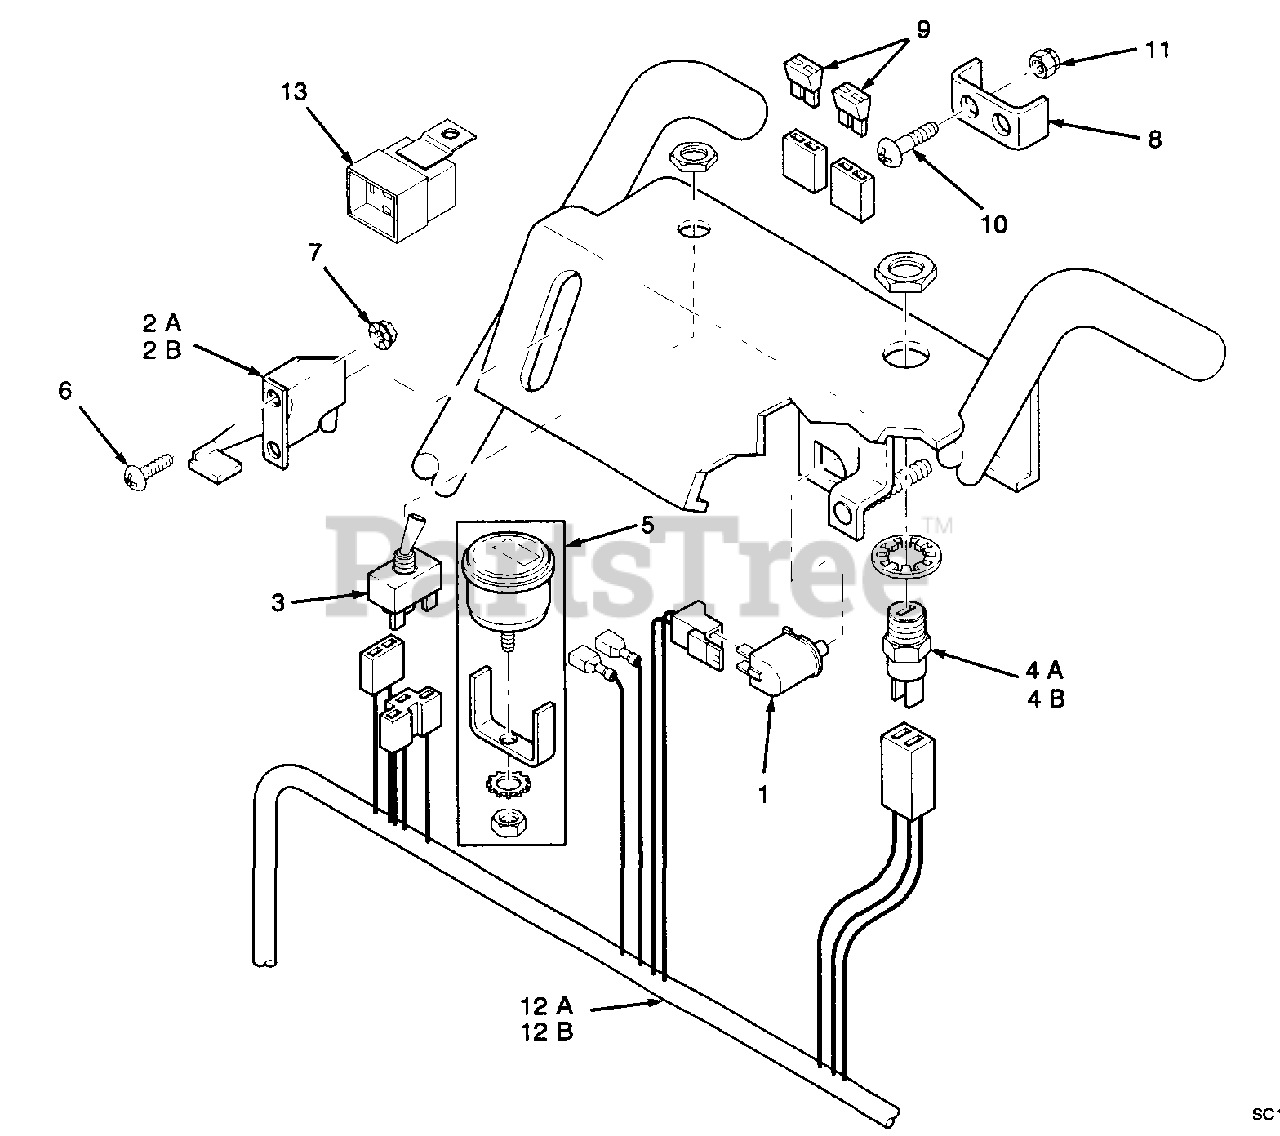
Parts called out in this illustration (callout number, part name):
1	Switch, Neutral Interlock
2A	Throttle Control
2B	Throttle Control
3	Engagement Switch, Electric Clutch
4A	Key Switch
4B	Key Switch
5	Hour Meter
6	Screw, #10-32 x .50 Phillips Washer Head
7	Nut, #10-32 Serrated Flange Hex Head
8	Bracket, Fuse Holder
9	Blade Fuse, 20A
11	Nut, #10-32 Elastic Stop
12A	Handle Wire Harness, Electric Start
12B	Handle Wire Harness, Manual Start
13	Relay
